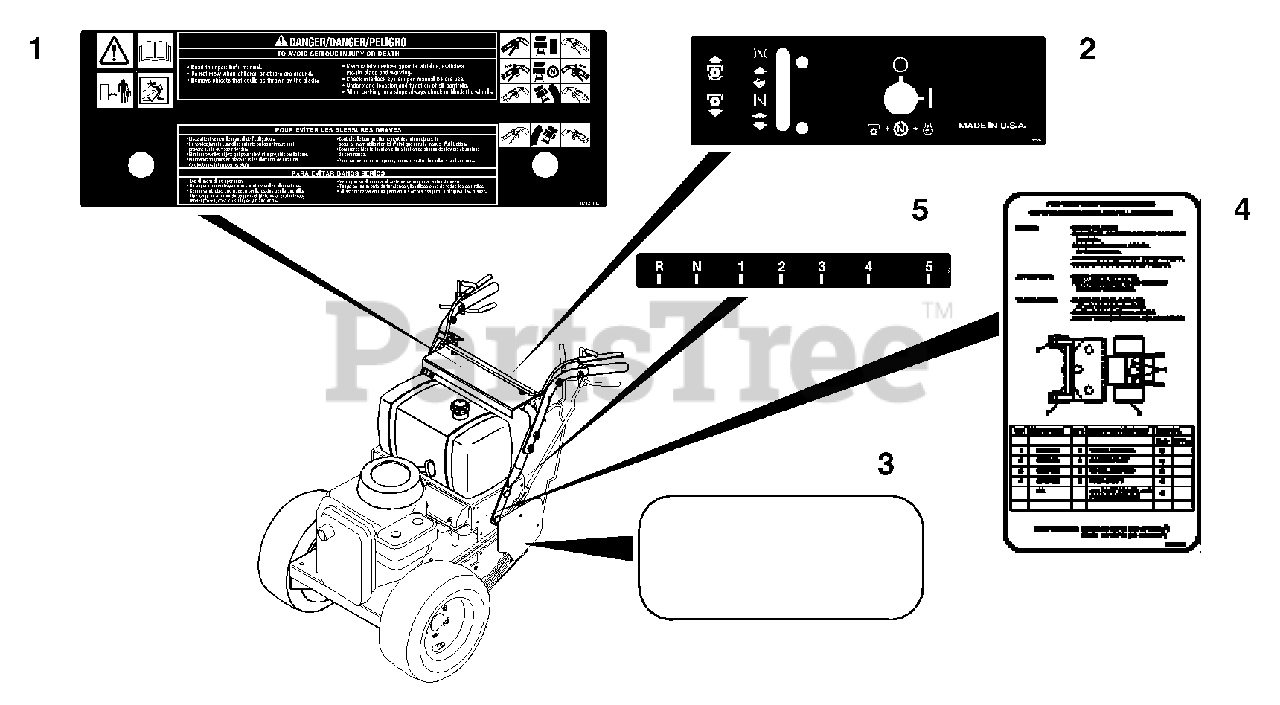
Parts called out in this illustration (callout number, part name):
1	DECAL PRO-150 SAFETY
2	DECAL, PRO-150 DASH PANEL
3	DECAL, PRO-150 12.5HP
4	DECAL, PRO-150 MAINTENANCE
5	DECAL, SHIFTER
